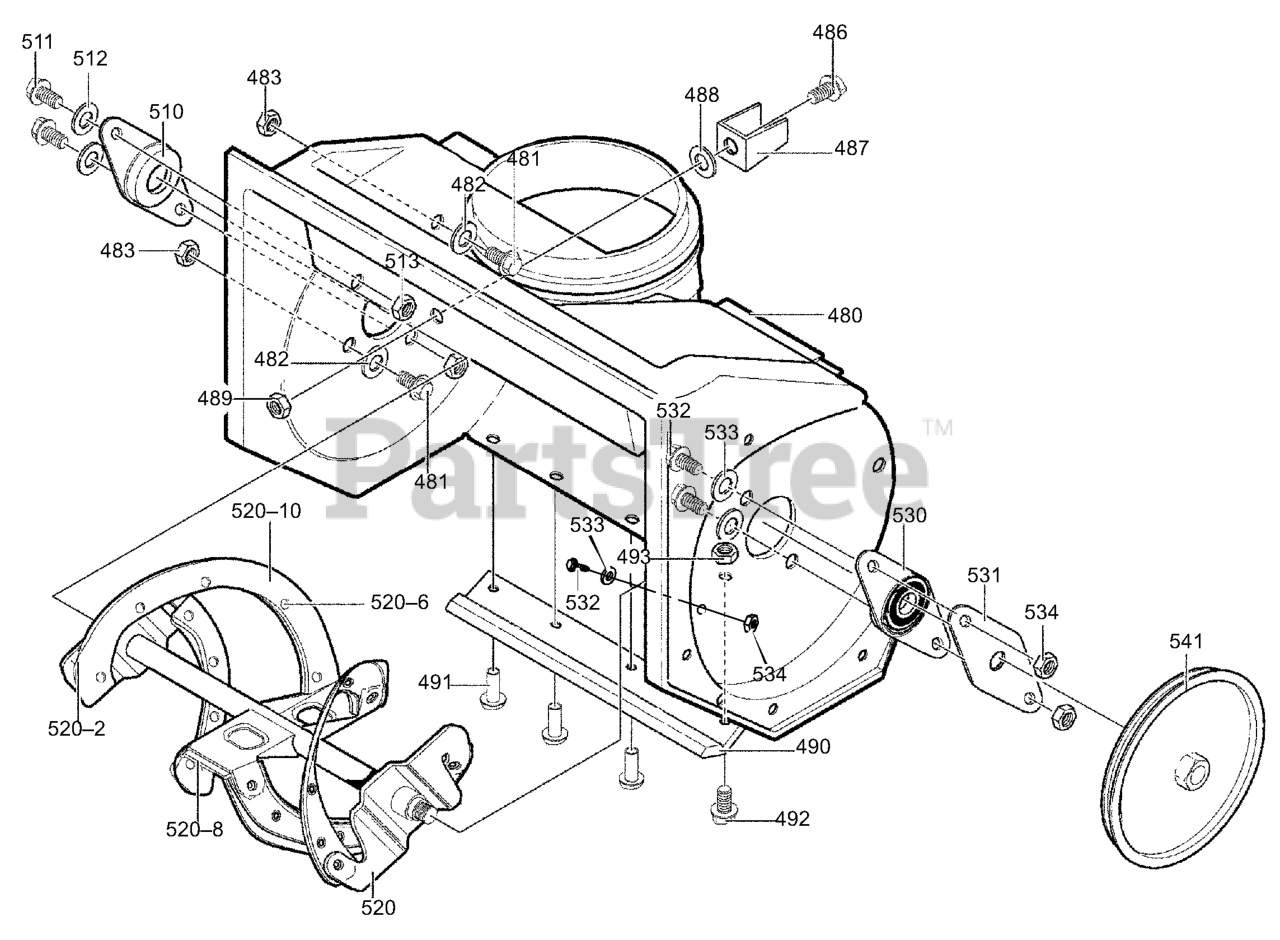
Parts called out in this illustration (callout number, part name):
480	HOUSING, ASSY
481	SCREW, 1/4-20X.75
482	WASHER, FLAT
483	NUT, 1/4-20
486	SCREW, 1/4-20X.63
487	BRACKET, STOP
488	WASHER, FLAT
489	NUT, 1/4-20 HEX NYLOCK
490	BLADE, SCRAPER
491	RIVET
492	SCREW, 1/4-20X.75
493	NUT, 1/4-20
510	BEARING, FLANGE
511	SCREW, 1/4-20X1.00
512	WASHER, FLAT
513	NUT, CNTRLK 1/4-20
520	AUGER, ASSY
520-2	BLADE, AUGER
520-6	RIVET
520-8	BLADE, CENTER
520-10	AUGER & BLADE SUPPORT
530	BEARING & PLATE ASSY
531	PLATE, RETAINER
532	SCREW, 1/4-20X.63
533	WASHER, FLAT
534	NUT, 1/4-20
